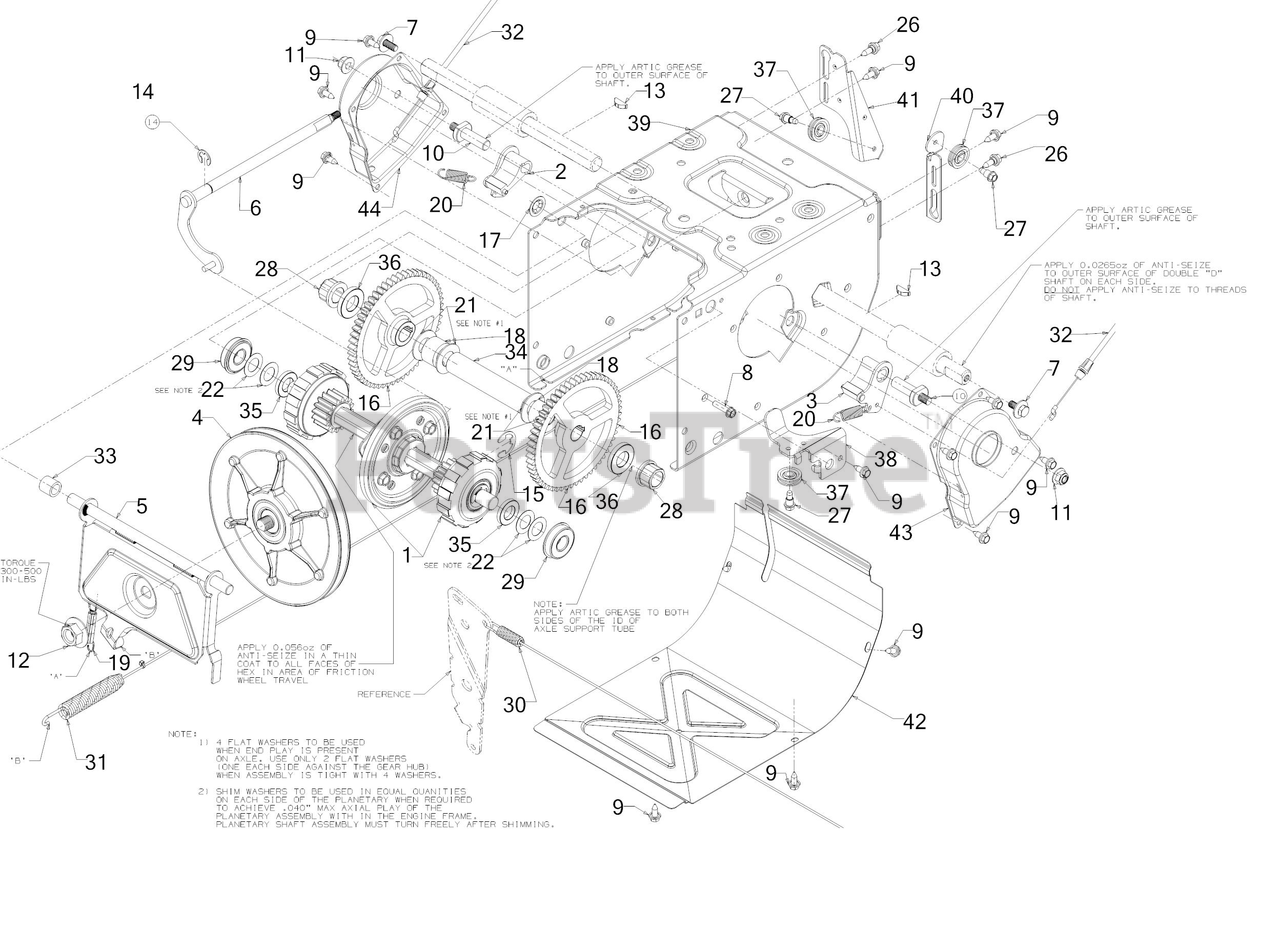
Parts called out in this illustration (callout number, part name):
1	PLANETARY SHIFT ASSEMBLY
1	FRICTION WHEEL ASSEMBLY
2	DOGG ASSEMBLY (RH)
3	DOGG ASSEMBLY (LH)
4	FRICTION WHEEL DISC ASSEMBLY
5	FRICTION WHEEL BRACKET
6	SHIFT ROD ASSEMBLY
7	SCREW 5/16-24 x .750 GR5
8	SCREW 1/4-20 x 1.00
9	SCREW 1/4-20X.625
10	ACTUATOR SHAFT
12	FLANGE NUT 5/8-18
13	KEY 3/16 x 3/4
14	E-RING FOR .500
15	RETAINING RING
18	SPACER: .76ID x .75
19	EXTENSION SPRING
20	EXTENSION SPRING
21	FLAT WASHER .760ID X1.49OD x .06
22	FLAT WASHER .67X 1.174X .02
26	SHOULDER SCREW
27	SHOULDER SCREW
28	FLANGE BEARING
29	BALL BEARING
30	AUGER DRIVE CABLE 47.48"
31	WHEEL DRIVE CABLE 44.955"
32	STEERING CABLE
33	SPACER-.513 ID x .703 OD x .69
34	AXLE SUPPORT TUBE
36	AXLE SPACER
37	CABLE GUIDE ROLLER
38	AUGER CABLE BRACKET
40	AUGER CABLE GUIDE BRACKET
41	GUIDE BRACKET
